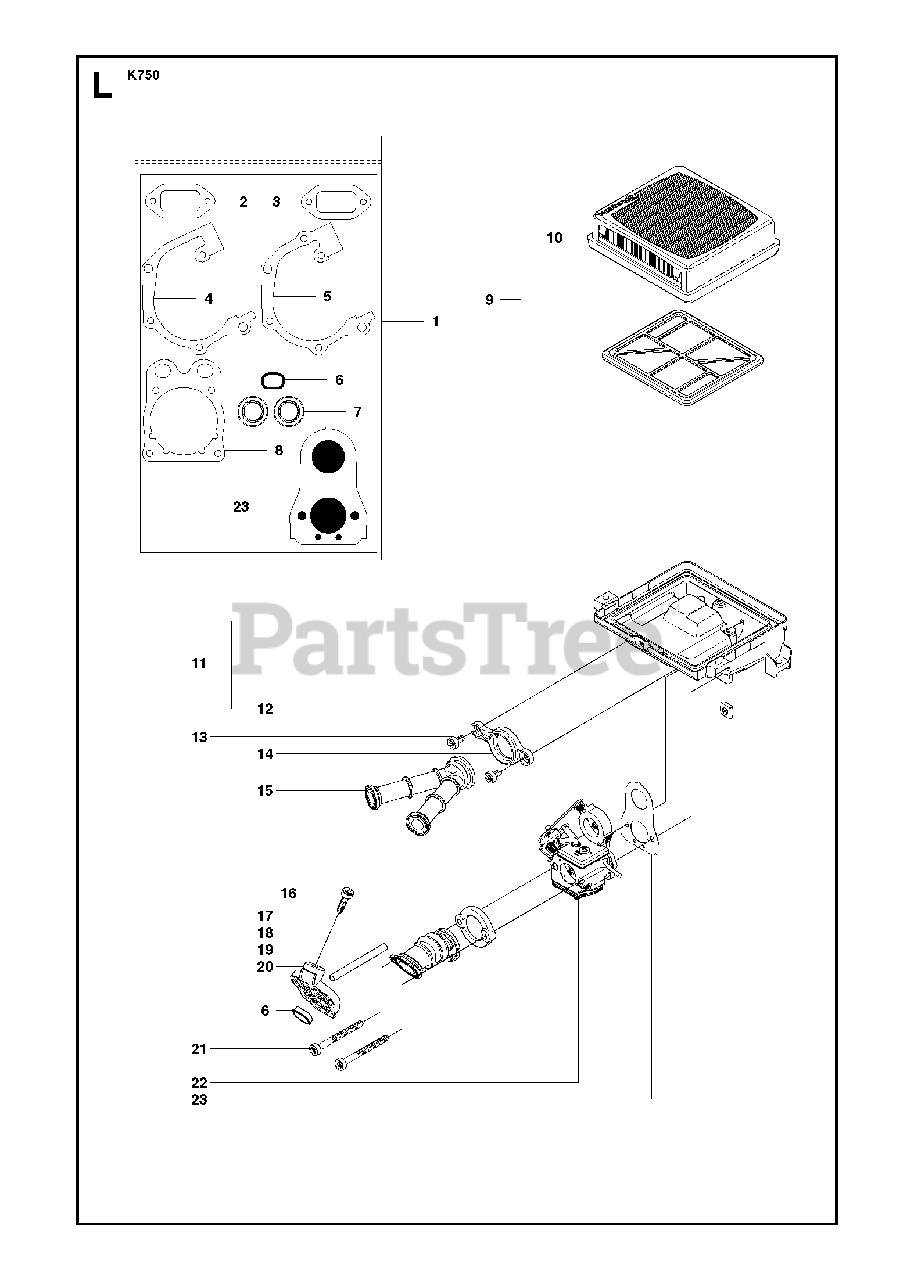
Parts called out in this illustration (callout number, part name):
1	GASKET KITIncl. 2 - 8, 23
3	GASKET
7	SEALING RING
9	FILTERIncl. 10
10	AIR FILTER
11	CARBURETTOR BRACKETIncl. 12
13	SCREW ITXSCM
14	FLANGE INLET PIPE
15	INLET PIPE
16	SCREW ITXSCM
17	FLANGE INLET PIPE
18	INLET PIPE
19	IMPULSE HOSE
21	SCREW ITXSCM
22	CARBURETTORZama C3-EL29
22	CARBURETTORJapan only
23	GASKET
